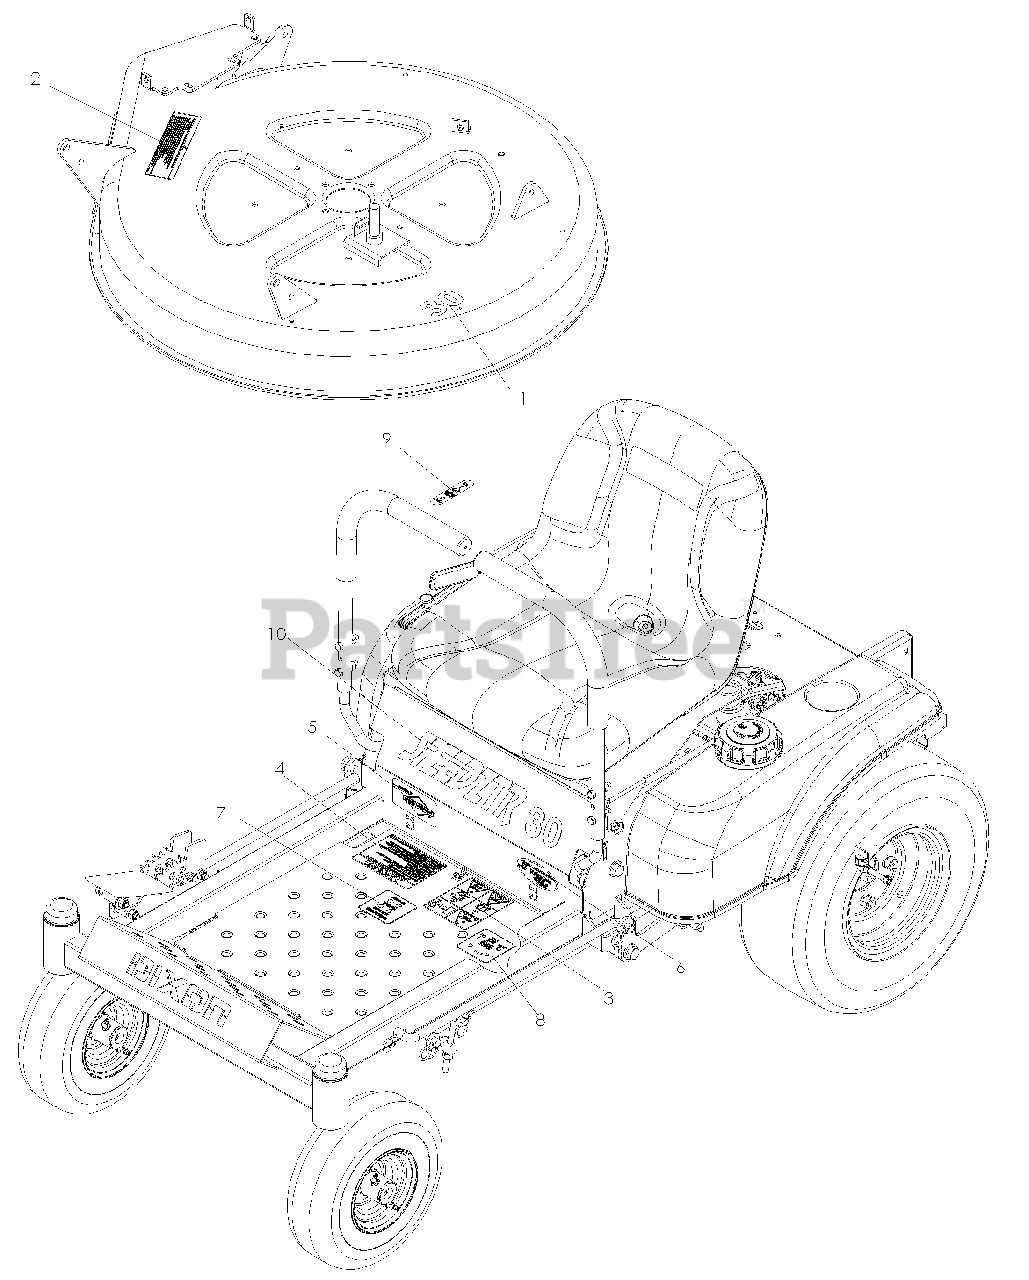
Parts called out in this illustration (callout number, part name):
1	DECAL, 30"
2	DECAL, DISCHARGE, MULTILINGUAL
3	DECAL, WARNING
4	DECAL, WARNING
6	HG DECAL(BLN-52241)
7	DECAL, DRIVE LEVERS
8	DECAL, BLADE DRIVE
9	DECAL, PARK BRAKE
10	DECAL, SPEEDZTR 30
